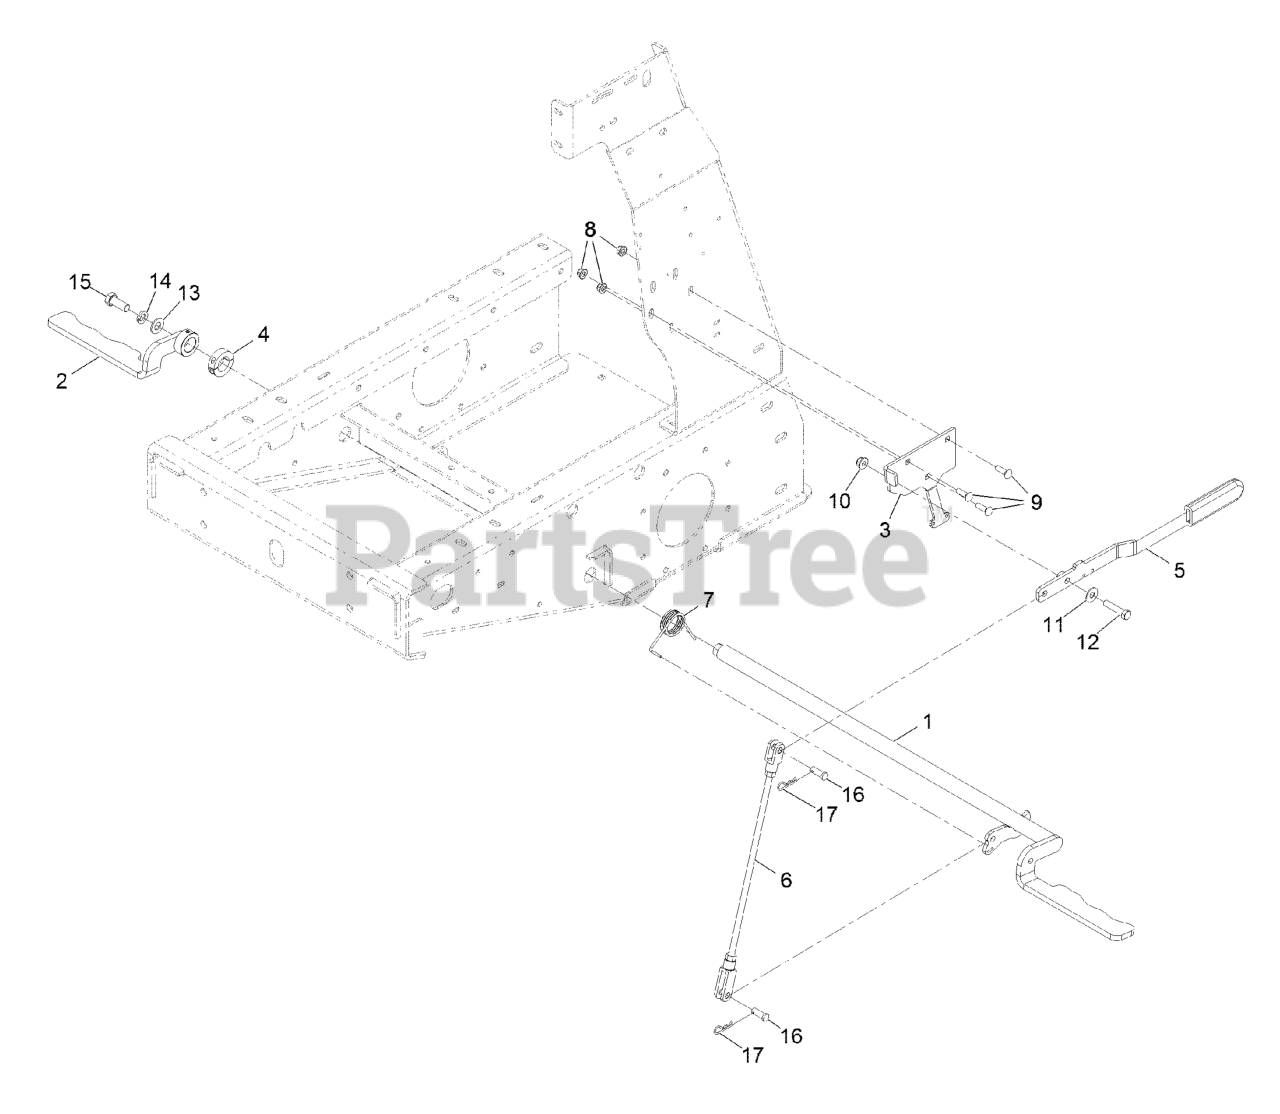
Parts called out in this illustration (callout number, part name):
1	Arm-Brake, Lt [black]
2	Arm-Brake, Rt [black]
3	BRACKET-HANDLE, BRAKE
4	COLLAR-LOCKING
5	ASM, Handle-Brake
6	ASM, Rod-Brake
7	SPRING-TORSION
8	Nut-Hex Flange
9	Bolt,Carriage,5/16-18X1,ST/ST 18-8
10	NUT-HF, NI
11	WASHER-FLAT
12	SCREW-HH
13	WASHER-FLAT
14	WASHER-LOCK
15	Screw ( .50-20Unfx1.25 Grade 8]
16	PIN-CLEVIS
17	Pin-Hair
